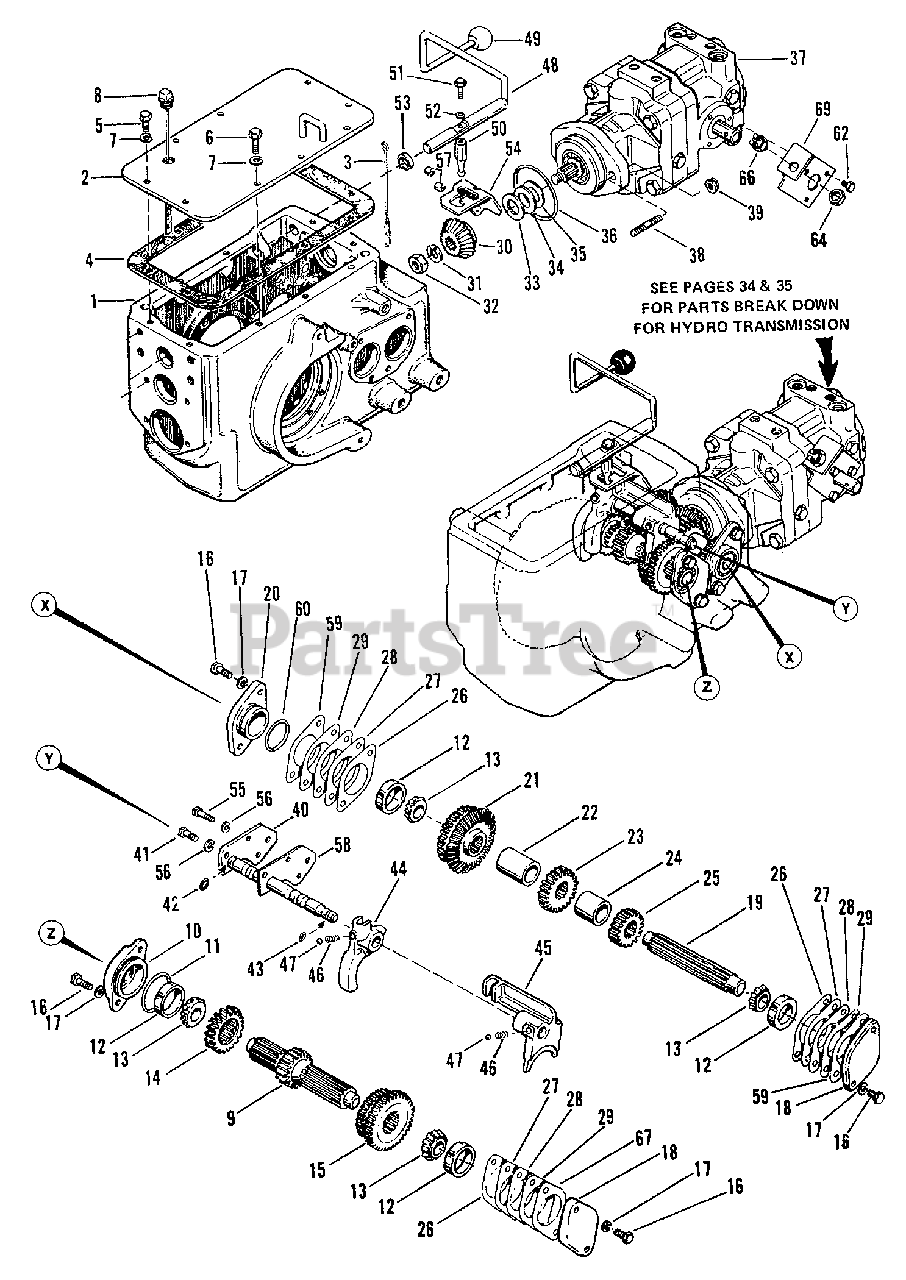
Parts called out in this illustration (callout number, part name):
1	CASE, Differential
2	COVER ASSEMBLY
5	CAPSCREW, Hex, 3/8"-16 x 3/4" Lg.
6	CAPSCREW, Hex, 3/8"-16 x 1" Lg.
7	LOCKWASHER, 3/8"
8	DIP STICK ASSEMBLY
9	SLIDING GEAR SHAFT
10	CAP, Bearing
11	RING, "O"
12	CUP, Bearing
13	CONE, Bearing
14	GEAR, 20T
15	GEAR, Lo and 2nd
16	CAPSCREW, Hex, 3/8"-16 x 7/8" Lg.
17	LOCKWASHER, 3/8"
18	CAP, Bearing
19	SHAFT, Input
20	CAP, Bearing
21	BEVEL GEAR ASSEMBLY
23	GEAR, 23T
25	GEAR, 18T
26	SHIM, .002 as required
27	SHIM, .003 as required
28	SHIM, .005 as required
29	SHIM, .010 as required
30	PINION, Bevel, 24T
32	NUT, Hex, Jam, 1/2"-20
33	SHIM, .002 as required
34	SHIM, .003 as required
35	SHIM, .005 as required
36	RING, "O"
37	HYDRO MOTOR, w/Pump
39	LOCKNUT, Whiz
40	SHIFT SHAFT ASSEMBLY
41	CAPSCREW, Hex, 3/8"-16 x 3/4" Lg.
43	RING, "O"
44	FORK, Shift Hi
45	FORK, Shift Lo, 2nd
48	SHIFTER SHAFT ASSEMBLY
50	STEM, Shift
51	CAPSCREW, Hex, 5/16"-18 x 1" Lg
52	LOCKWASHER, 5/16
54	GUIDE, Shift
55	CAPSCREW, Hex, 1/4"-20 x 1" Lg.
56	WASHER, Seal
59	SHIM PACK, .030
60	RING, "O"
61	BRACKET, Mounting
62	SCREW, Washer Head, 1/4-20 x 1/2" Lg.
63	NUT, 9/16"-18
